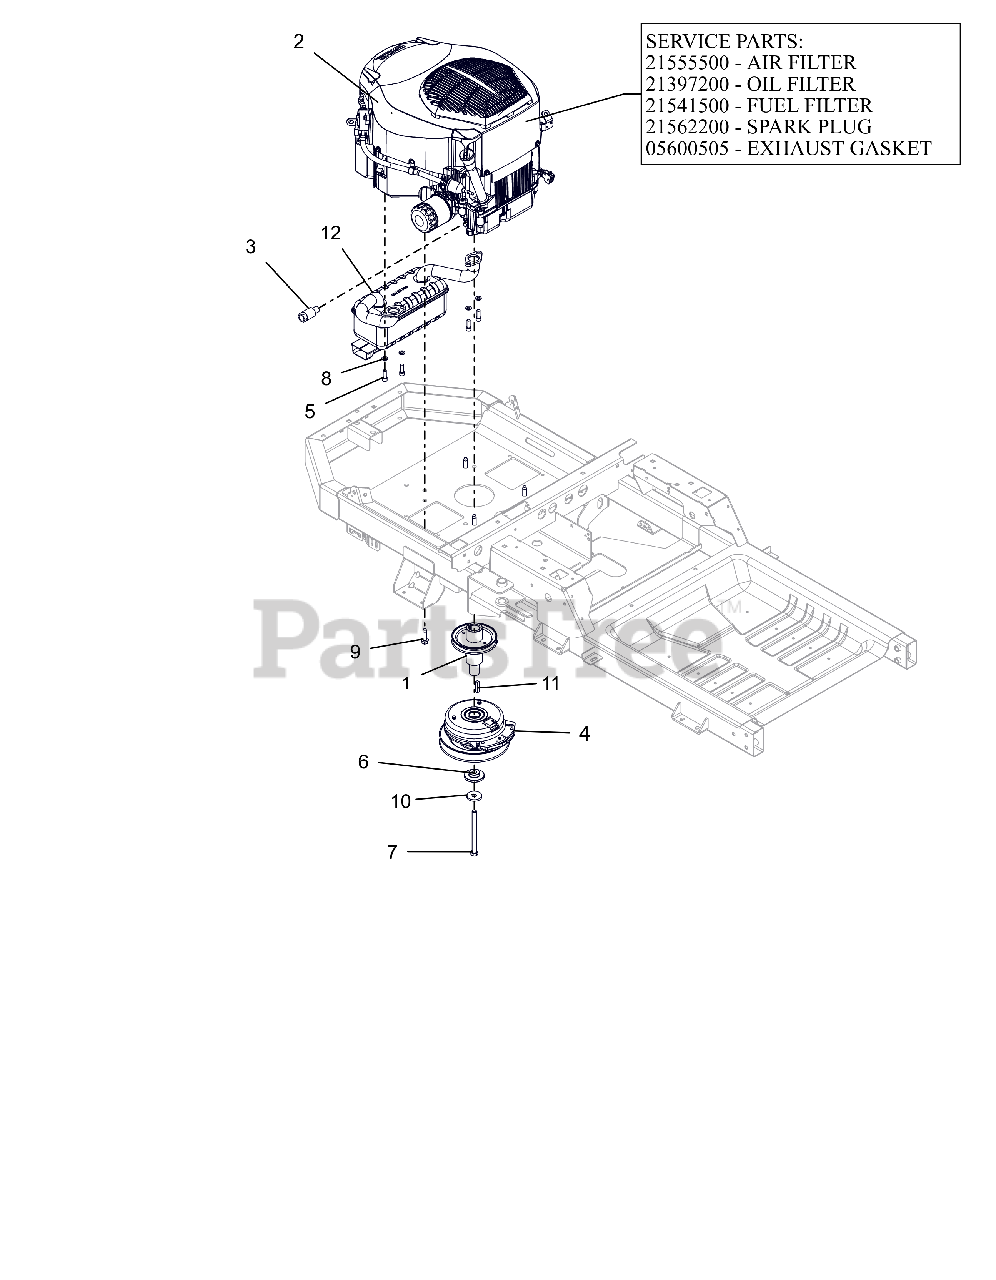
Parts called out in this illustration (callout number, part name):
1	WLDMT, DRIVE SHEAVE (LG XL)CZC
2	ENGINE, KOHLER TWIN - 25HP
2	AIR CLEANER, KOHLER
2	FILTER, OIL - KOH CV20
2	FILTER, FUEL
2	PLUG, SPARK (RFI)
2	GASKET, MUFFLER COURAGE TWIN
3	DRAIN, OIL
4	CLUTCH,105FTLB MONOPOLE 6.83"
5	SCR-CAP .31-18X.88 S/HD G8 ZCC
6	BSHG-FLG .469X1.06X.574X2.0
7	BLT-HEX.438-20X5 GR8 YZ NYTORQ
8	WSHR,LK-REG .312X.078 ZCC
9	SCR,TAP .375-16X1.25HWH TR ZCC
10	WASHER, 7/16" SPRING DISK
11	KEY-SQ .25 X 1.25 X .25 SAE
12	MUFFLER, KOHLER
